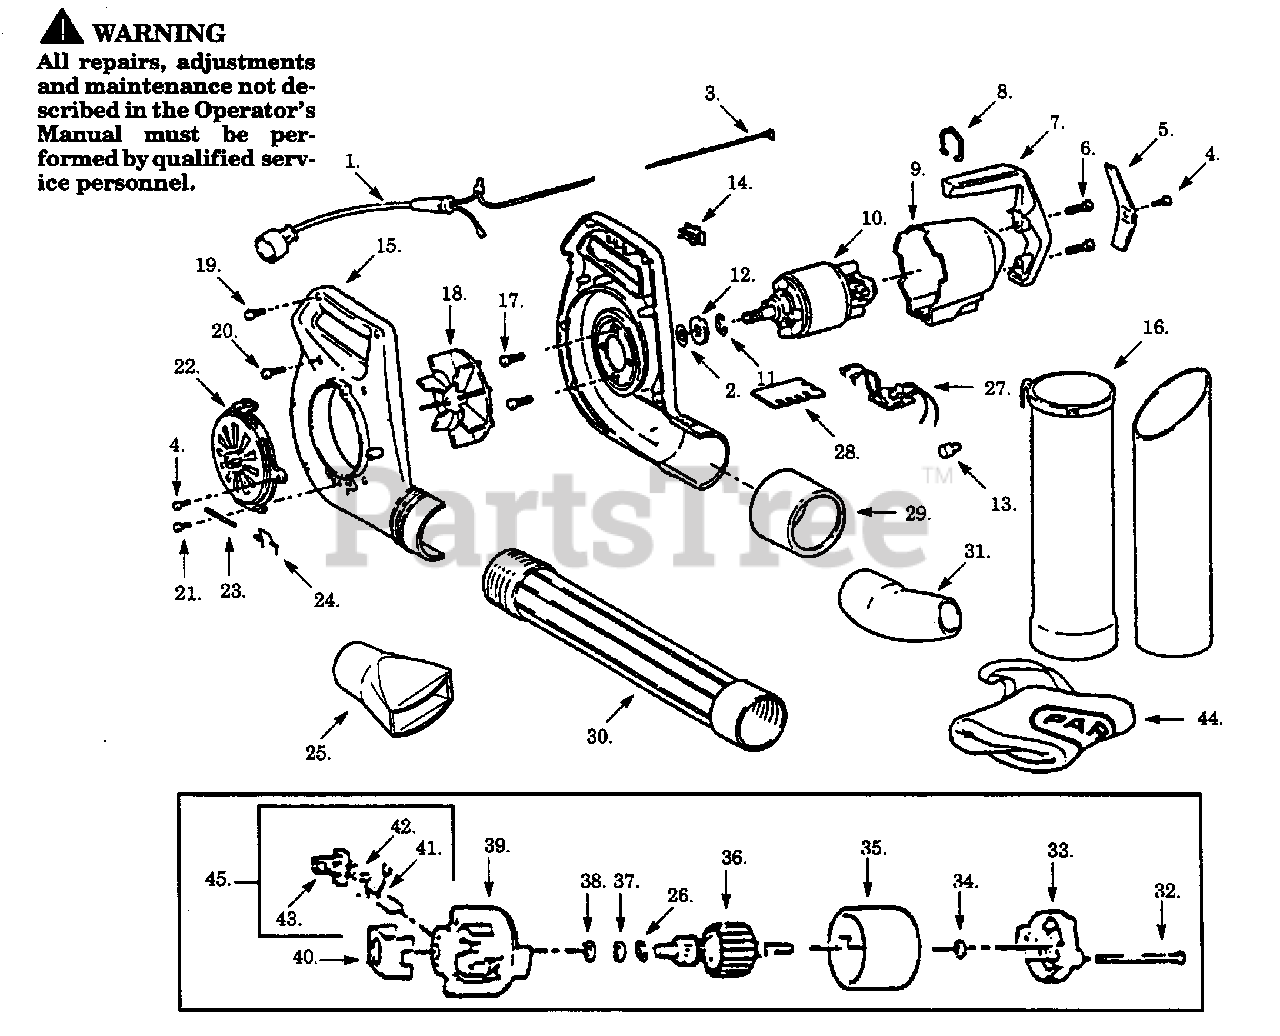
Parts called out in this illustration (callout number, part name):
1	Power Cord Ass'y.
3	Leadwire Ass'y.(Black)
7	Side Handle
9	Motor Cover
10	Motor Ass'y.
11	Retaining Ring
13	Terminal Connector
14	On/Off Switch
15	Housing Set
16	Vacuum Tube
18	Impeller Ass'y.
22	Inlet Cover Ass'y.
23	Pin Hinge
24	Return Spring
25	Nozzle Diffuser
26	Retaining Ring
27	P.C. Board Ass'y.
28	Mounting Board
29	Ferrule Sleeve
30	Upper Tube
33	Endbell Ass'y. (Drive)
35	Field Ass'y.
36	Armature Ass'y.
39	Endbell Ass'y. (Brush)
40	Insulator
42	Brush Spring
43	Brush Holder
44	Vacuum Bag
45	Brush Kit (Incl. 41,42,43)
